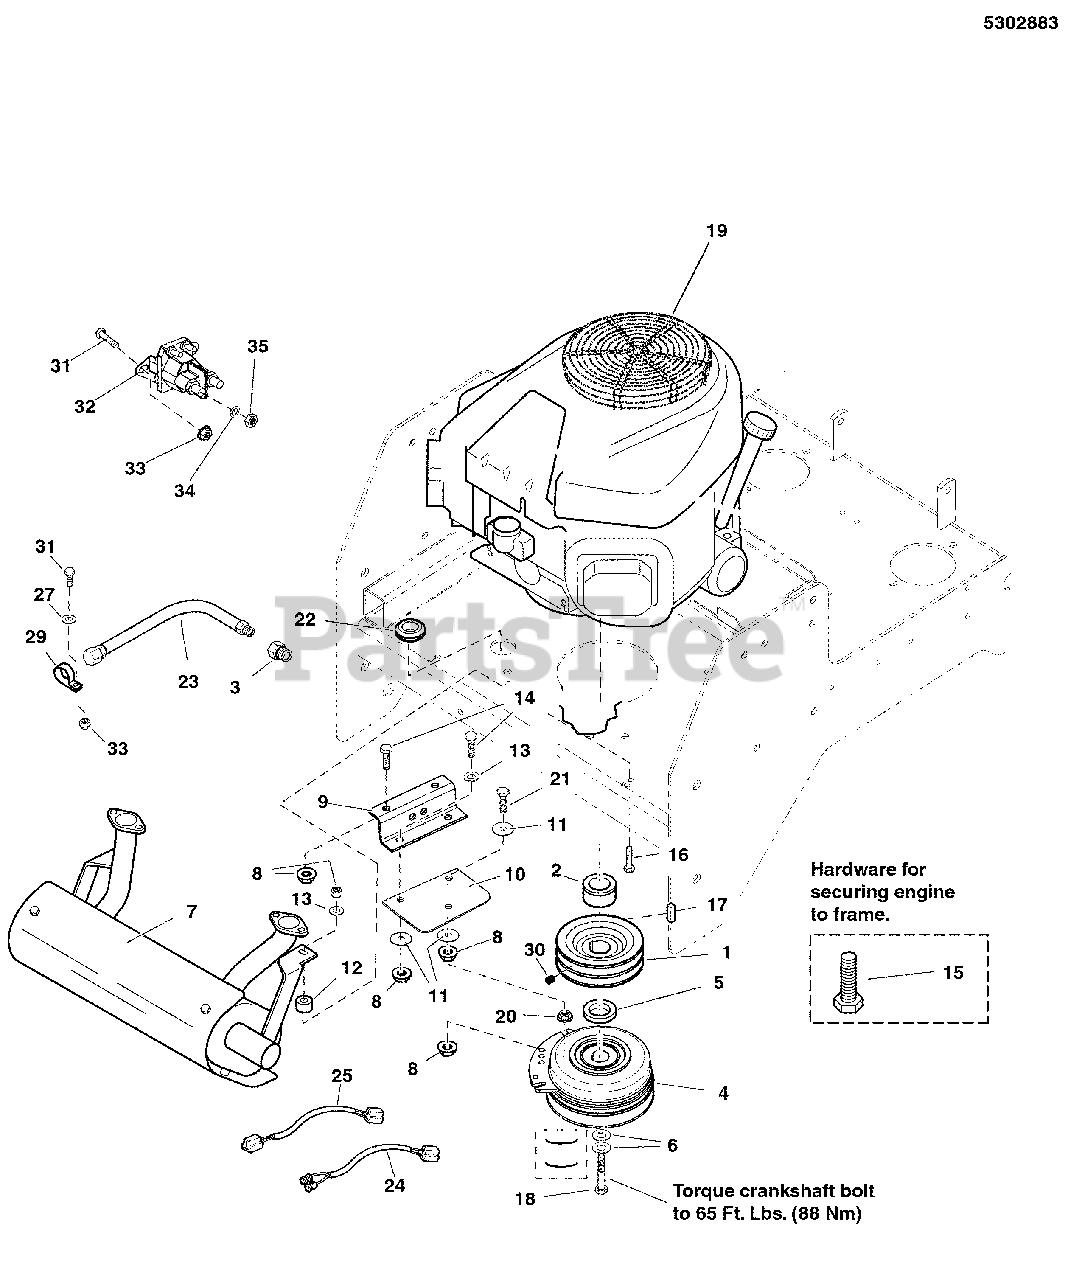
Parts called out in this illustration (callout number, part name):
1	PULLEY, CRANKSHAFT, 1.126 ID X 4.75 OD
2	SPACER, 1.13 X 1.75 X 1.03, CZ
3	ADAPTER, Oil Drain
4	CLUTCH WARNER 200 FT-LB 1.13 X 6.323
5	SPACER, 1.13 X 1.75 X .375
6	BELLEVILLE WASHER, 1.1875 X .442 X .098
7	MUFFLER, 27HP KAWASAKI, 5" CAN
8	NUT, 5/16-18 HEX NYLOCK FLANGE NUT
9	ANCHOR, CLUTCH - BLK
10	CLUTCH ANCHOR PAD
11	WASHER, .34 X 1.25 X 10 GA
12	SPACER, .39 X 1.00 X .80, CZ
13	WASHER, 5/16" SAE
14	BOLT, 5/16-18 X 1" GRD5 YZ
15	BOLT, HEX FLG, SER, GD5 3/8-16 X 1-1/4" PACH CZ
16	BOLT, 5/16-18 X 1-3/4" GD5 YZ
17	KEY, 1/4 SQ X 1
18	BOLT, CRANKSHAFT,7/16-20X2-1/2, GD8
19	ENGINE, KAWASAKI
20	NUT, 5/16-18 HEX SERRATED FLANGE (LARGE)
21	BOLT, 5/16-18 X 2-1/4 TFL, GD5 YZ
22	GROMMET, 7/8"
23	HOSE, OIL DRAIN
24	KIT, CLUTCH WIRE REPAIR
25	WIRE HARNESS, JUMPER, WARNER CLUTCH (SV)
27	WASHER, 1/4 SAE
29	CLAMP, VINYL INSULATED, 1.00
30	SET SCREW, 5/16-18 X 3/8, KNURL, W/PATCH
31	BOLT, 1/4"-20 X 3/4" GD5 YZ
32	SOLENOID-4 POLE 12 VOLT DC (TROMBETTA)
33	NUT, 1/4-20 HEX SERR. FLANGE
34	WASHER, Light Lock, 5/16
35	NUT, Hex Jam, 5/16-24
